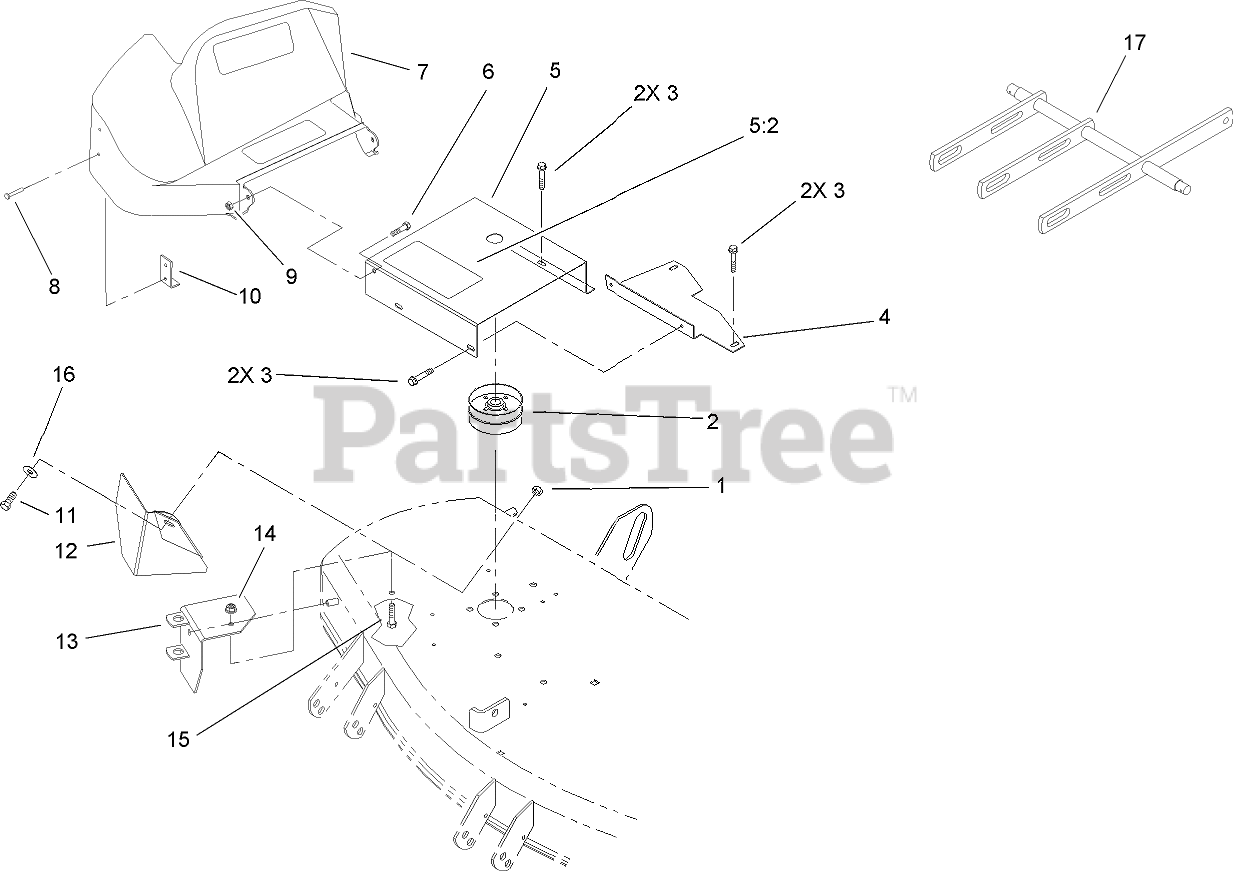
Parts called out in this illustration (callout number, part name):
1	NUT-LOCK, NI
2	PULLEY
3	SCREW-HWH
4	ADAPTER-SHIELD
5	SHIELD / DECAL ASM
5:2	DECAL-DANGER
6	SCREW-HH
7	SHIELD-BELT
8	RIVET-POP
9	NUT-LOCK, NI
10	BRACKET-SUPPORT, SHIELD
11	SCREW-HH
12	Deflector
13	Pivot Bracket ASM
14	NUT-HF
15	SCREW-HH
16	WASHER-FLAT
17	BAR-LEVELER
